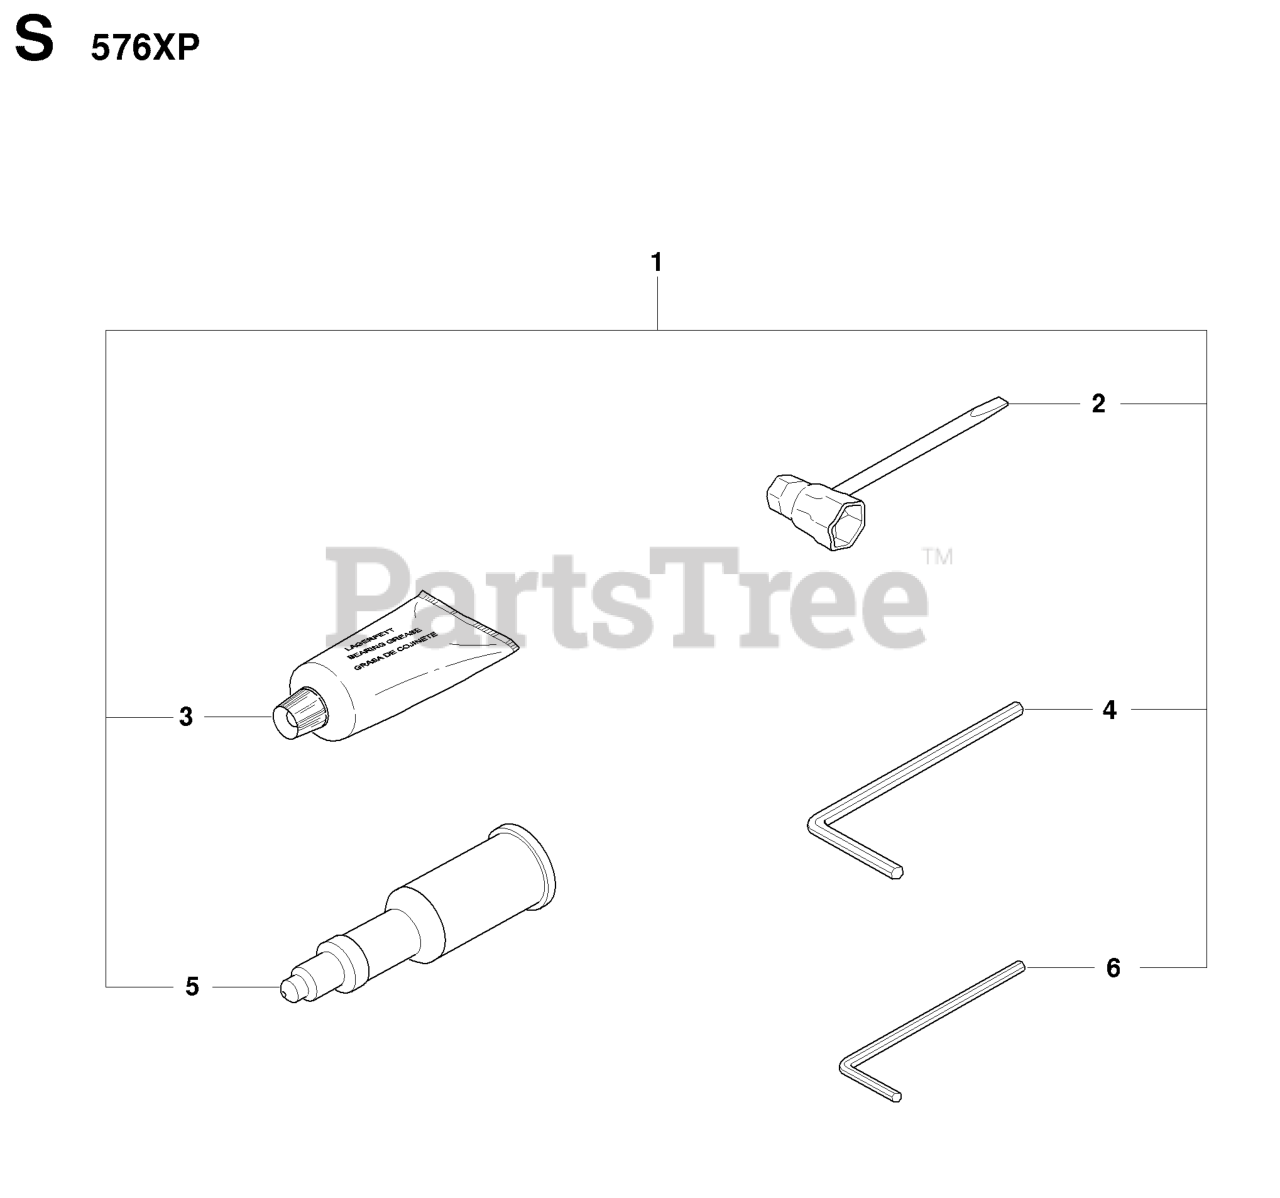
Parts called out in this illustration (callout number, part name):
1	TOOL KIT
2	COMBI TOOL
3	GREASE
5	Grease Gun
